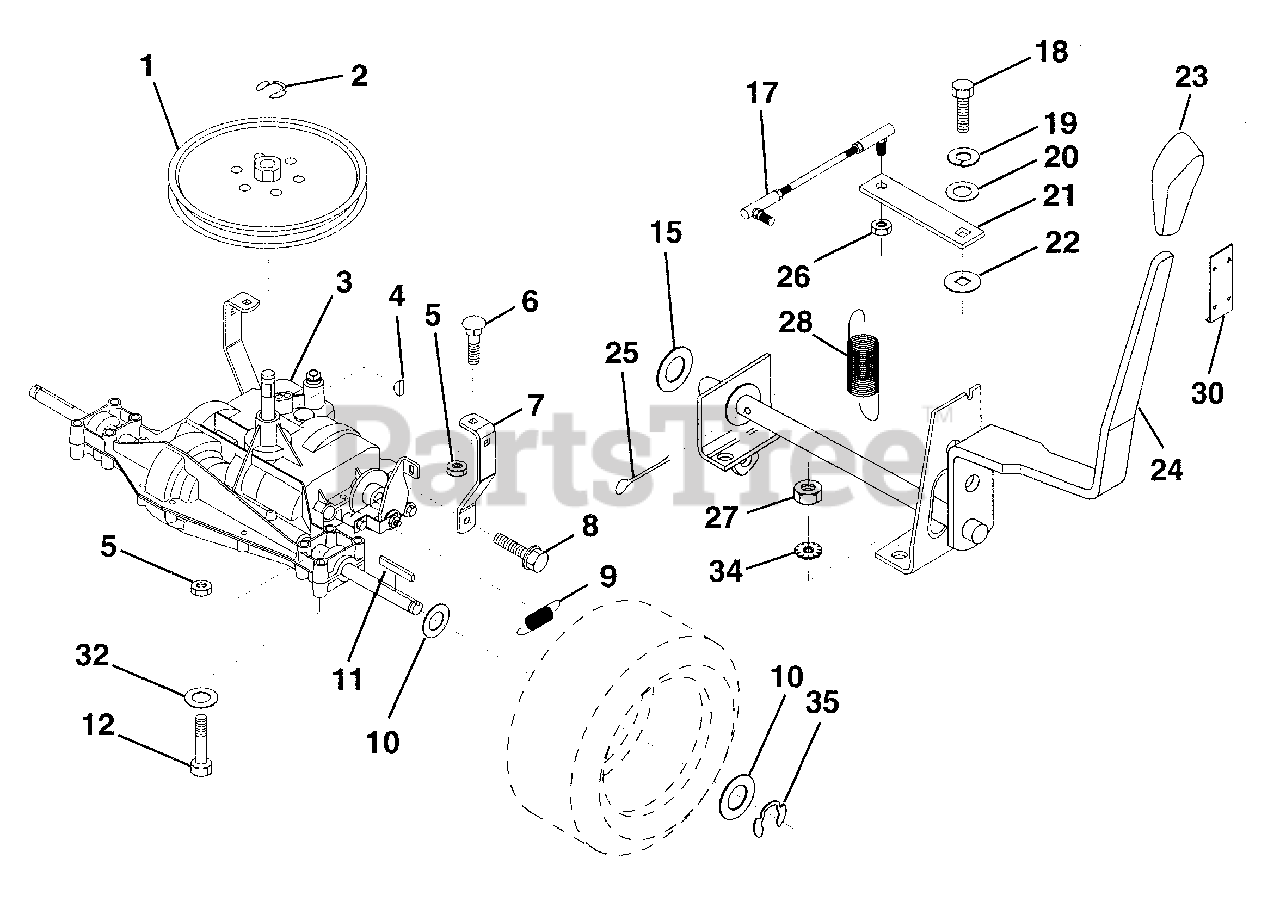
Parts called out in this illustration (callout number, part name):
2	Ring, Retainer
3	Transaxle, Peerless, 6 Speed,
4	Key, Woodruff #9
5	Nut, Hex, Crownlock 5/16-18
6	Bolt, Carriage 5/16-18 UNC x 3/4
7	Strap, Torque
8	Screw 5/16-18 x 3/4
9	Spring, Brake
10	Washer 25/32 x 1-1/4 x 16 Gauge
11	Key, Square
12	Bolt, Hex, Fin. 5/16-18 x 2-1/2
15	Washer 17/32 x 1 x 16 Gauge
17	Link, Shift
18	Bolt, Hex, Fin. 1/4-28 UNF x 3/4 Grade 8
19	Washer, Lock 1/4
20	Washer 9/32 x 3/4 x 10 Gauge
21	Arm, Shift
22	Washer, Shift Plate
23	Knob, Golfclub
24	Shift Handle Assembly
25	Pin, Cotter 1/8 x 1
26	Locknut 5/16-24 UNF
27	Nut, Hex, Keps 5/16-18
28	Extension, Spring
30	Retainer Knob
32	Washer 11/32 x 11 /16 x 16 Gauge
34	Washer, External Tooth 5/16
